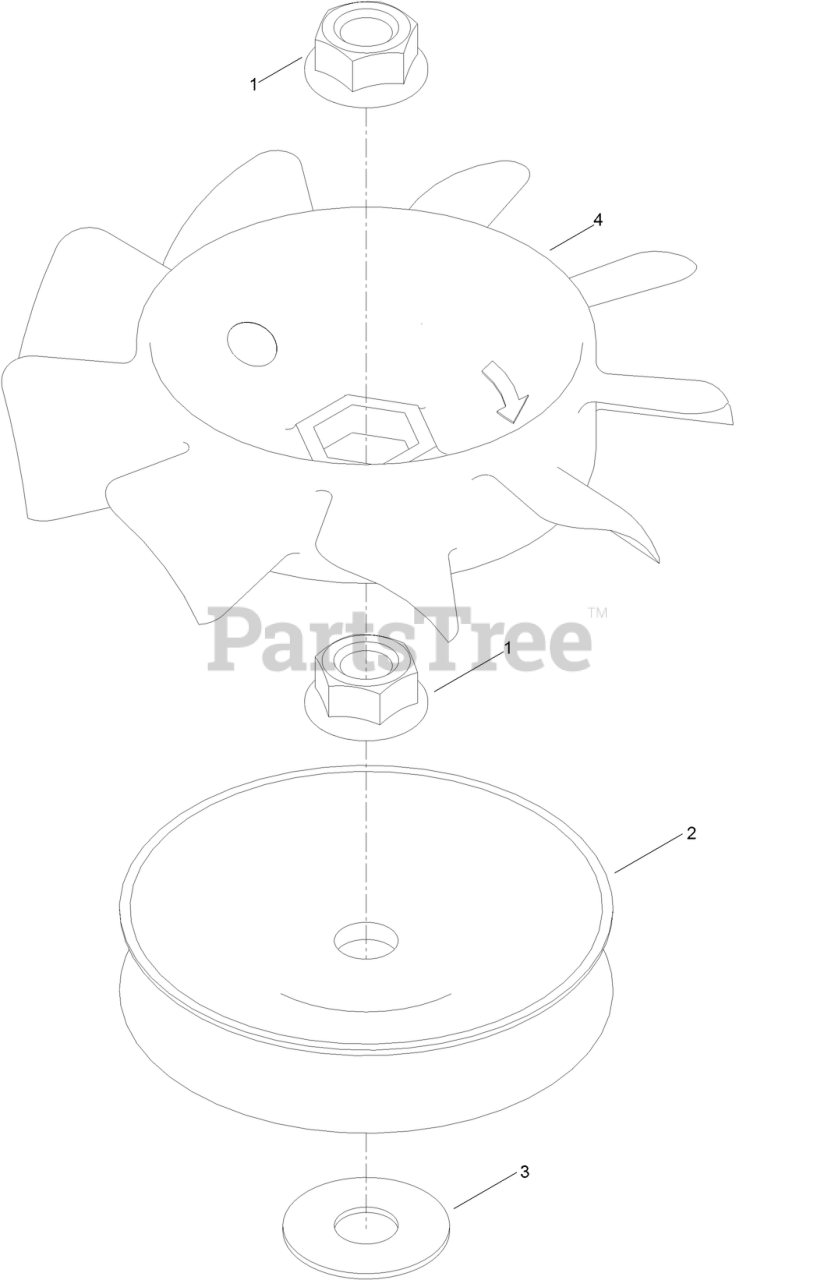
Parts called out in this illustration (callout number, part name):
1	NUT-FLANGE
2	PULLEY-STEEL
3	WASHER
